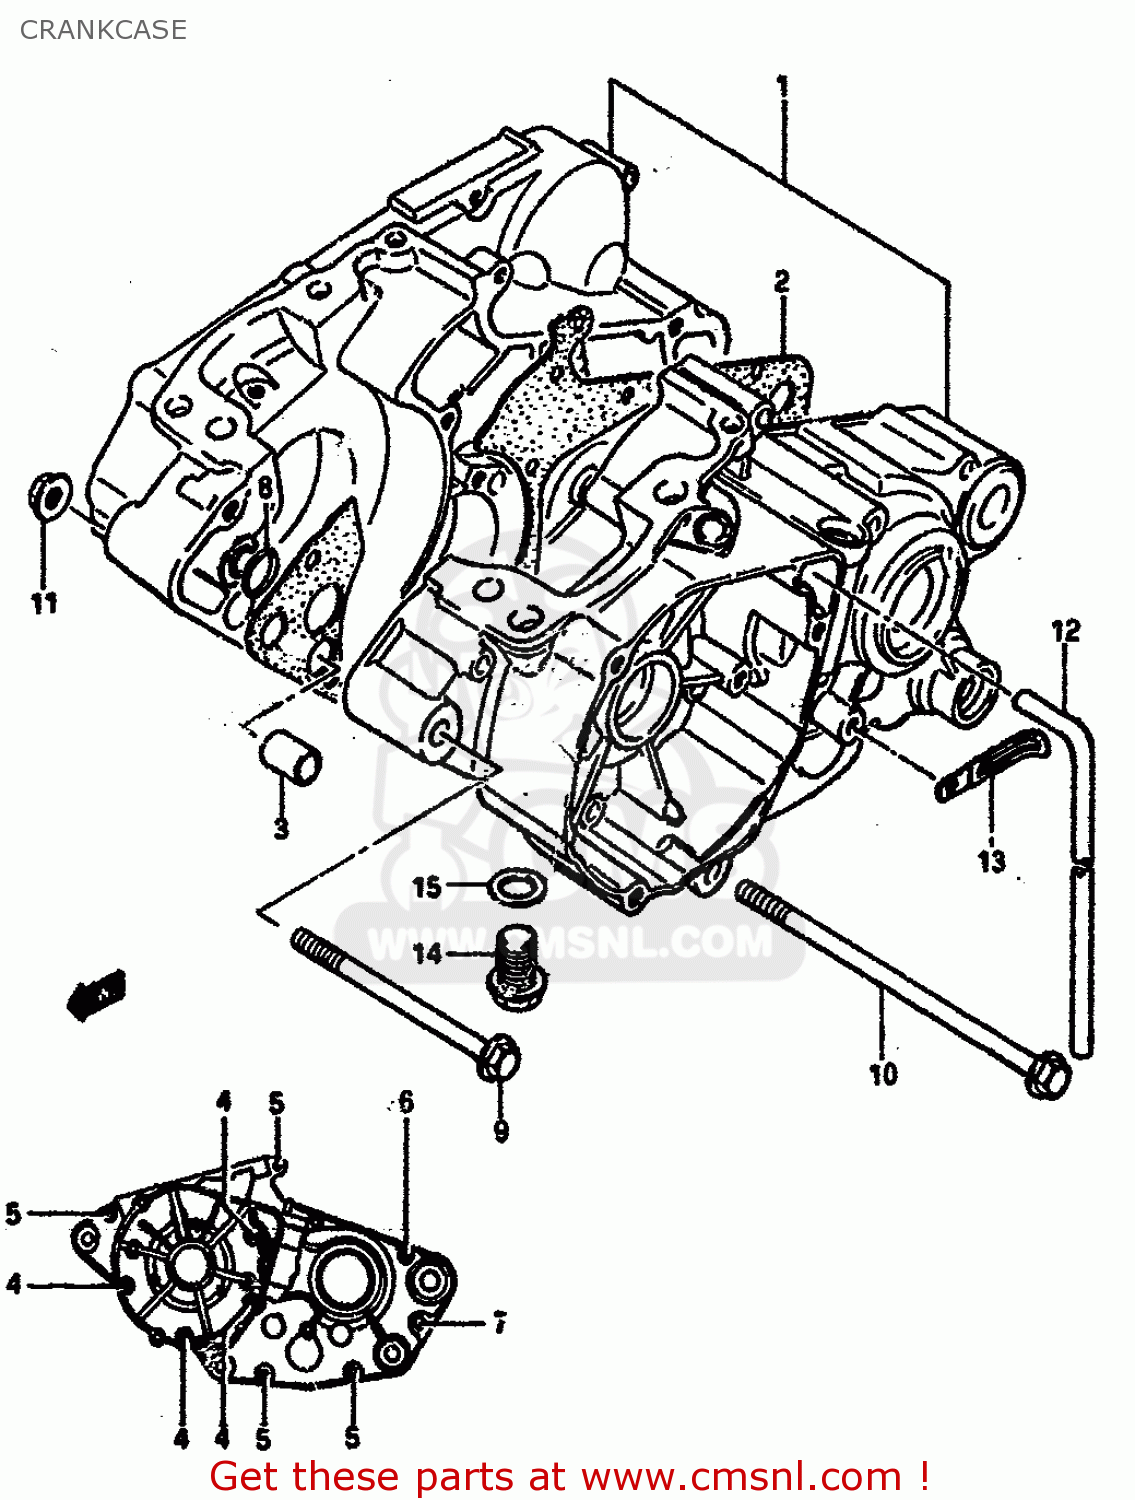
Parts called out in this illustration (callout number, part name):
1	CRANKCASE SET
2	GASKET,CRANKCASE (MCA)
3	PIN
4	SCREW
5	SCREW
6	SCREW
7	SCREW
8	O RING(D:1.9,ID:13.8)
9	BOLT(8X95)
10	BOLT(8X150)
11	NUT
12	HOSE
13	CLAMP
14	PLUG
15	GASKET(14X19.2X2) (NAS)
